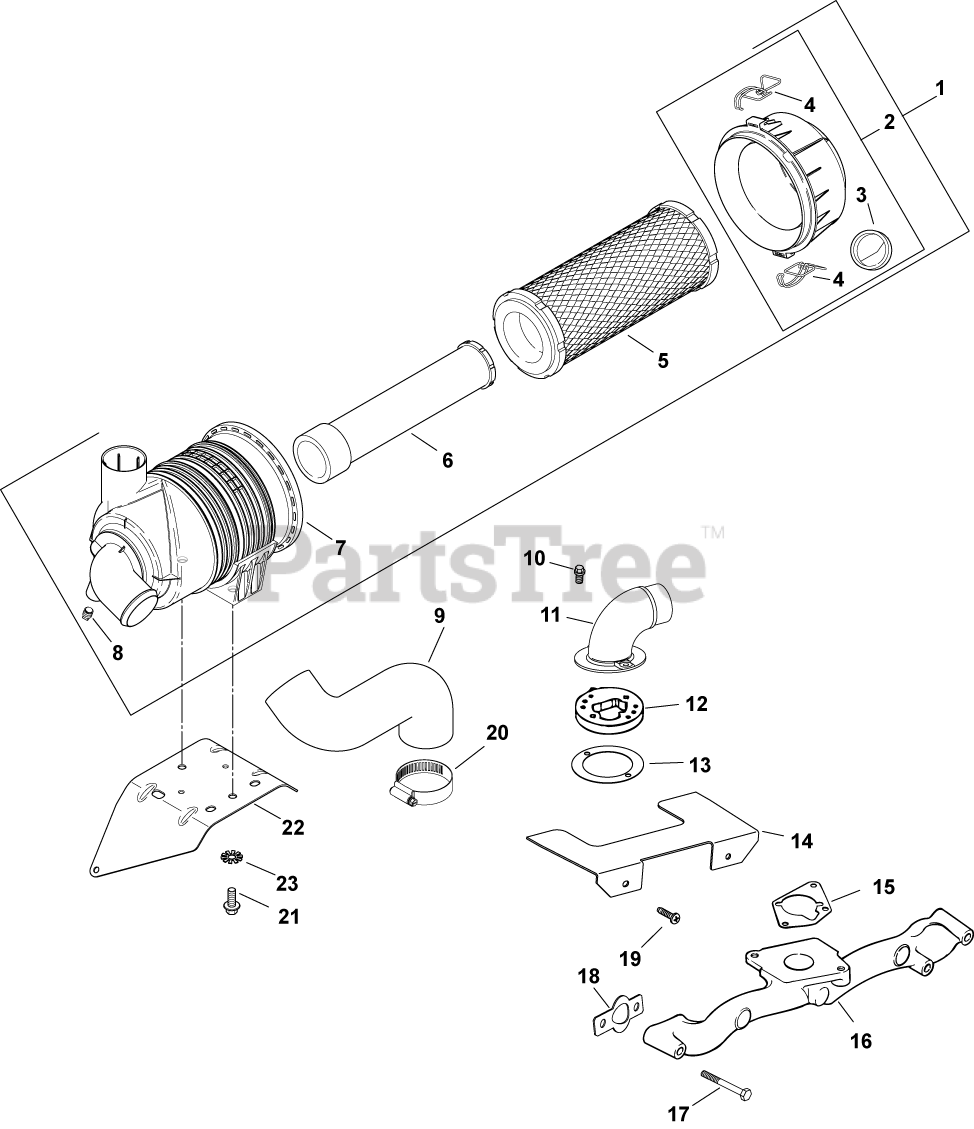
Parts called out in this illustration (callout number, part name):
1	AIR CLEANER, CANISTER
2	COVER ASSEMBLY, AIR CLEANER
3	VALVE, DUST EJECTOR
4	CLIP - USE 62 154 07-S
5	ELEMENT, AIR FILTER - PRIMARY
6	ELEMENT, AIR FILTER - SAFETY
7	HOUSING, HEAVY DUTY A/C
8	PLUG, PIPE
9	HOSE, AIR CLEANER
10	SCREW, FLG M6X1.0X16
11	ADAPTER, REMOTE AIR CLEANER
12	ADAPTER ASSY (CH18 / 20)-USE 24 029 97-S
13	GASKET, ADAPTER
14	SHIELD, DEBRIS
15	GASKET, AIR CLEANER BASE
16	MANIFOLD, METAL INTAKE
17	SCREW, FLG M6X1.0X55
18	GASKET, INTAKE MANIFOLD USE 24 041 79-S
19	SCREW, PHL HD 11-16X3/4"
20	CLAMP, HOSE-USE 25 237 21-S
21	SCREW, FLG M8X1.25X20
22	BRACKET, AIR CLEANER
23	WASHER,INT EXT TOOTH LOCK 5/16"
